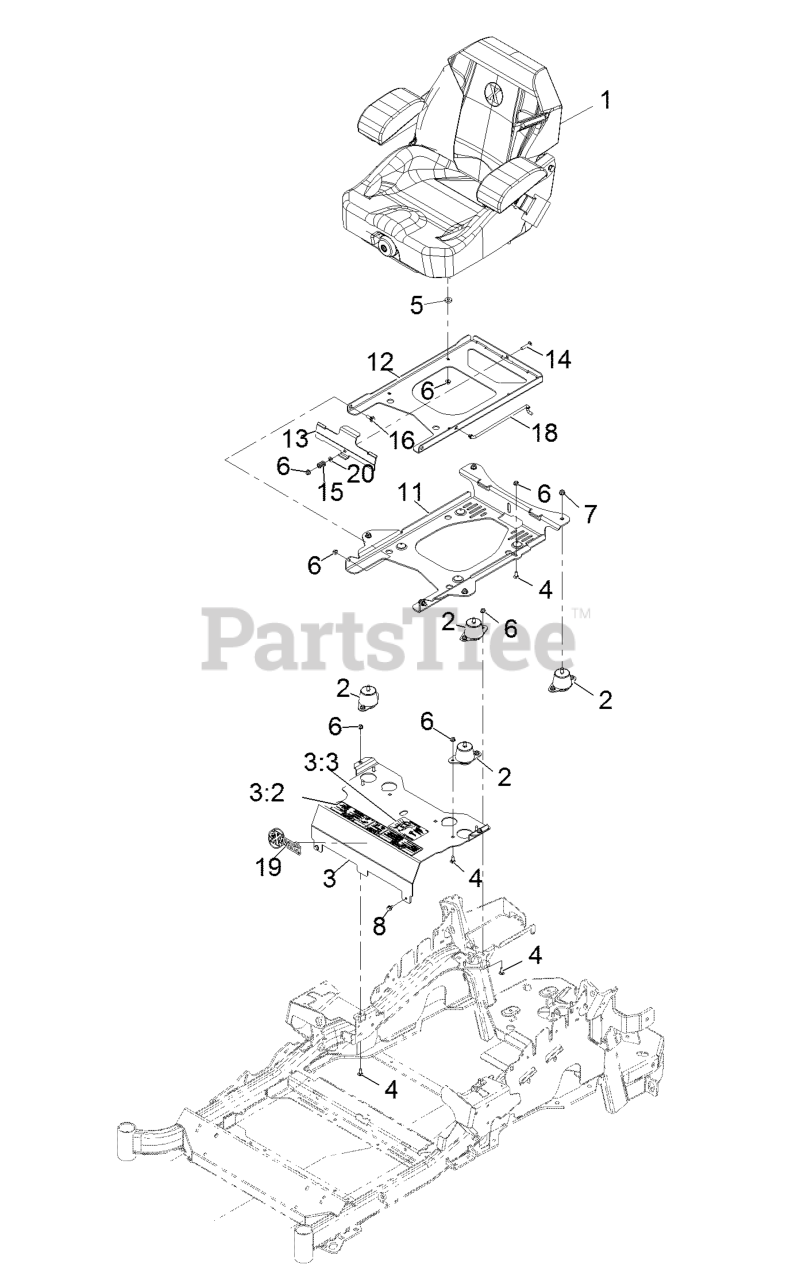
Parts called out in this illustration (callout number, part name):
1	KIT-SUSPENSION SEAT
2	ISOLATOR-SEAT
3	MOUNT-SEAT
3:2	DECAL-CONSOLE
3:3	DECAL-SERVICE AID
4	SCREW-CARR
6	NUT-HF, NI
7	NUT-HF, NI
11	PLATE-TILT, SEAT SUPPORT
12	PLATE-FRAME, SEAT
13	PLATE-LATCH, SEAT
14	BOLT-CARR
15	SPRING-COMPRESSION
16	SCREW-SHOULDER
18	ROD-PROP
20	WASHER-PLAIN
